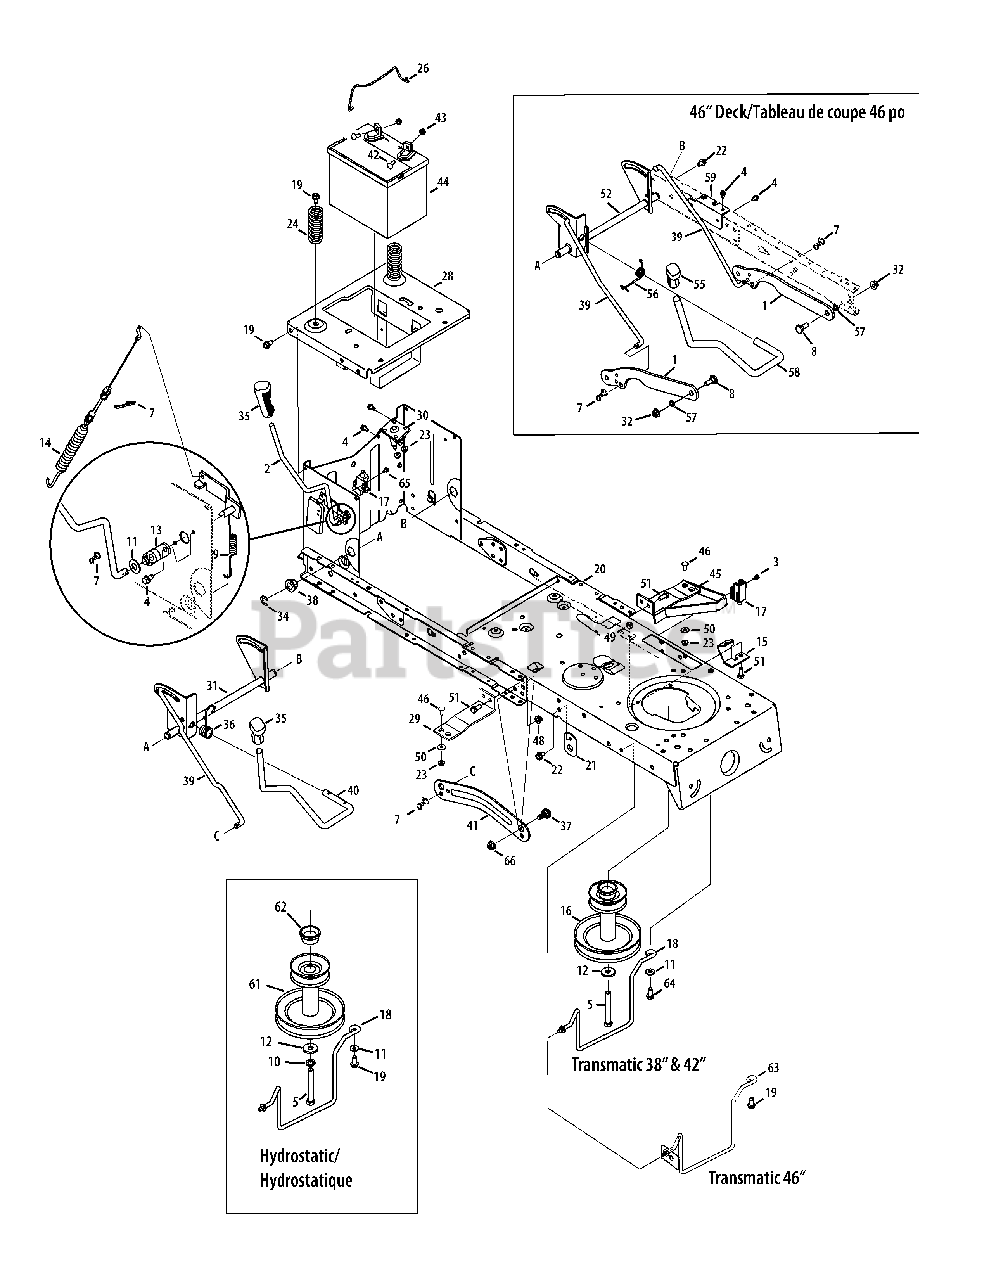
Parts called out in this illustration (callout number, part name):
1	Deck Lift Link
2	PTO Handle
3	Shoulder Scr #10-16 x .50" Lg.
4	Hex Wash S-Tapp Scr 1/4-20 x .50
5	Hex Hd. Cap Scr. 7/16-20 x 3.25 Gr. 5 (38/42")
7	Bow Tie Cotter Pin
8	Shoulder Screw .5 x .270 : 3/8-16
9	Extension Spring
10	Lockwasher 7/16 ID
11	Flat Washer .385 ID x .87 OD x .06 (38/42")
12	Flat Washer .450 x 1.25 x .164
13	PTO Bearing
14	Deck Engagement Cable
15	Frame Support Bracket Orange
16	Engine Pulley 3.39 x 6.12 dia. (38/42")
17	Interlock Switch
18	Belt Keeper Rod (42" Deck)
19	S-Tapp Scr 5/16-18 x .75
20	Frame Orange
21	Pedal Support Bracket Orange
22	Hex Wash HD TT Scr 5/16-18 x .625
23	Hex L-Flanged Nut 1/4-20 Gr. F, Nylon
24	Compression Spring 1.314 OD x 2.55
26	Battery Hold Down Rod
28	Seat Frame Bracket
29	Running Board Bracket Orange
30	Solenoid
31	Lift Shaft (38" & 42")
32	Flange Lock-Nut 3/8-16 Gr. F, Nylon
34	"E" Ring .625 Dia.
35	Handle Grip
36	Torsion Spring (38" & 42")
37	Shoulder Screw .625 x .175, 3/8-16
38	Hex Flange Bearing .630 ID
39	Lift Rod
40	Deck Lift Handle(42")
41	Deck Lift Arm RH Orange
41	Deck Lift Arm LH Orange
42	Hex Flg. Scr. 1/4-20 x .75 Gr. 5
43	Sems Hex Nut 1/4-20
44	Battery 245 CCA (Dry)
45	Support Bracket Ass’y
46	Carriage Bolt 1/4-20 x .75
48	Hex L-Flg Nut 5/16-18 Gr. F, Nylon
49	Hex L-Nut 5/16-18
50	Flat Washer .28 x .74 x .063
51	Hex Screw 5/16-18 x .75
52	Lift Shaft
56	Torsion Spring
57	Flat Washer .395 x .62 x .063
58	Deck Lift Handle
59	Brace Bracket
61	Engine Pulley 3.39 x 6.12 dia. (38/42")
62	Spacer 1.0 x 1.4 x .825
63	Belt Keeper Rod (46" Deck)
64	Scr 5/16-18 x .75
65	Shoulder Scr. .342 x .335: 1/4-28
66	Flg. L-Nut 3/8-16 Gr. F
